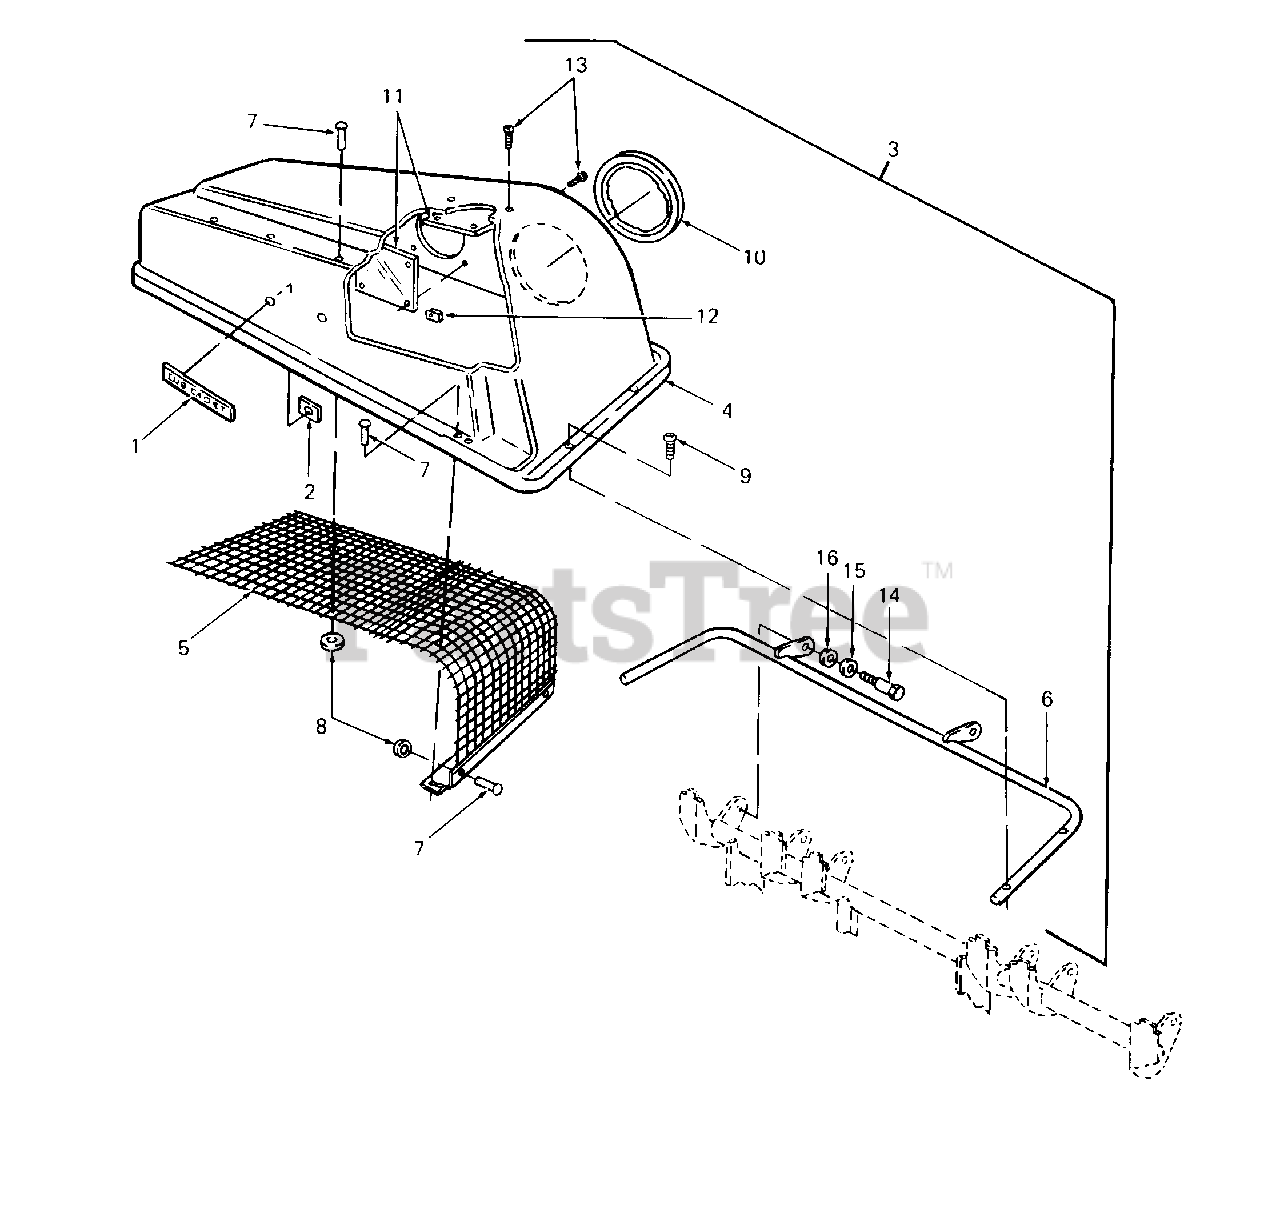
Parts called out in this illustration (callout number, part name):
1	Plaque, Logo w/Studs
2	Nut, Push-On Speed
3	Cover Assy, Grass Catcher
4	Order Grass Catcher Assy
5	Order Grass Catcher Assy
8	Washer, Flat, .218 x .62 x .063 Thk
9	Screw, Hex Wash Hd Tapp 1/4 X .50 Lg
10	Seal, Tube, 7.1 ID
11	Plate, Plastic, 1/8 Thk x 5.62 Sq
12	Nut, U-Type Speed
13	Screw, Truss Mach, #10 X .50 Lg
14	Screw, Shld
15	Washer, Flat, .510 x .75 x .033 Thk
16	Washer, bell, .515 x 1.14
